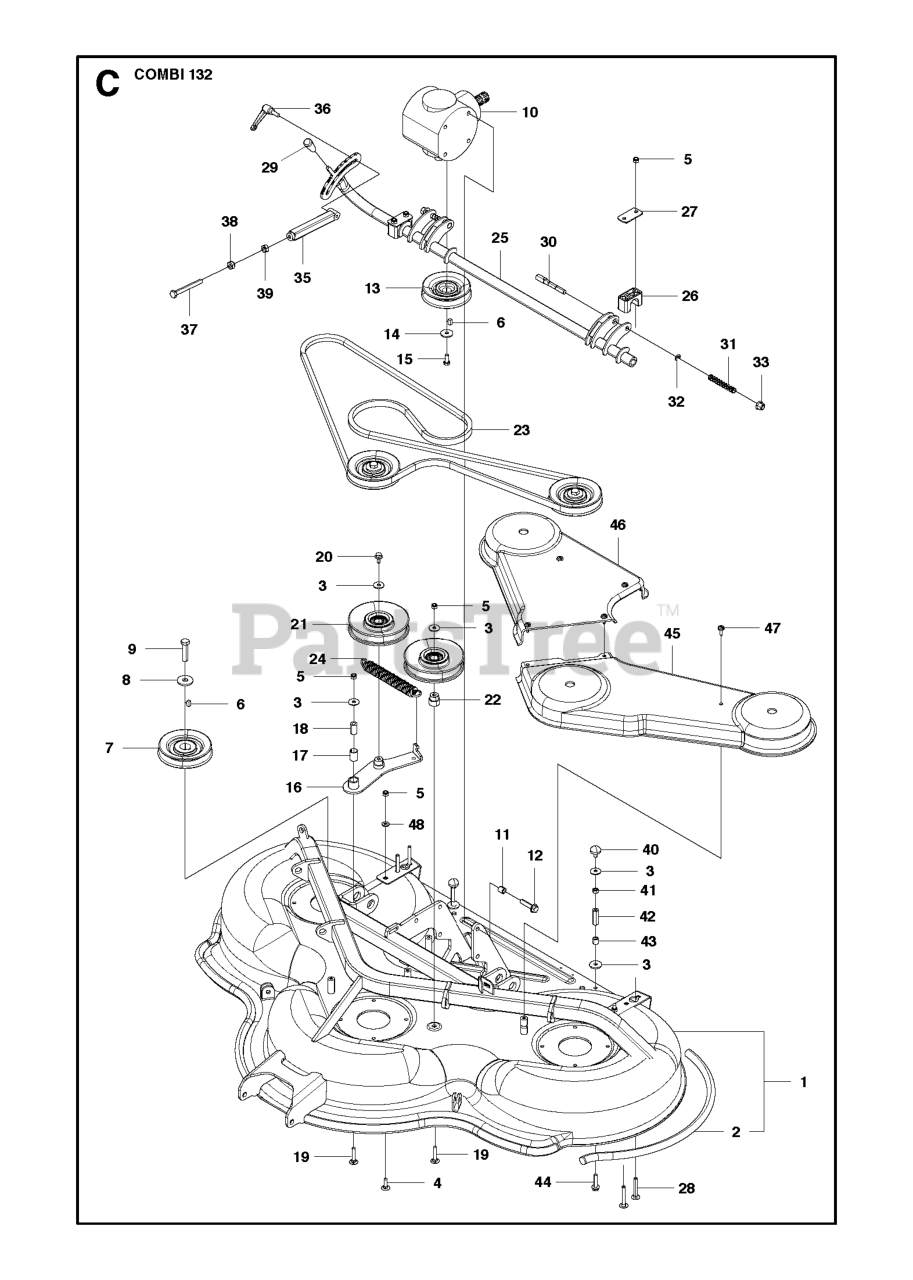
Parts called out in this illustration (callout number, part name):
5	LOCKNUT M8
10	BEVEL GEAR
13	PULLEY SPB DP106
16	BELT TENSIONER CUTTING DECK
19	Screw Mvbf 8 X 40
20	BOLT FLANGE - M8X16
24	DRAW SPRING L=122
35	PARALLEL ROD REPLACE -01
36	TURNING KNOB M 8
38	NUT
39	NUT
40	ANTIVIBRATION ELEMENT
41	NUT
44	SCREW EHHFM
45	BELT COVER C132 L_GREASEABLE
46	BELT COVER C132 R_GREASEABLE
48	WASHER BRB 8.4X17
